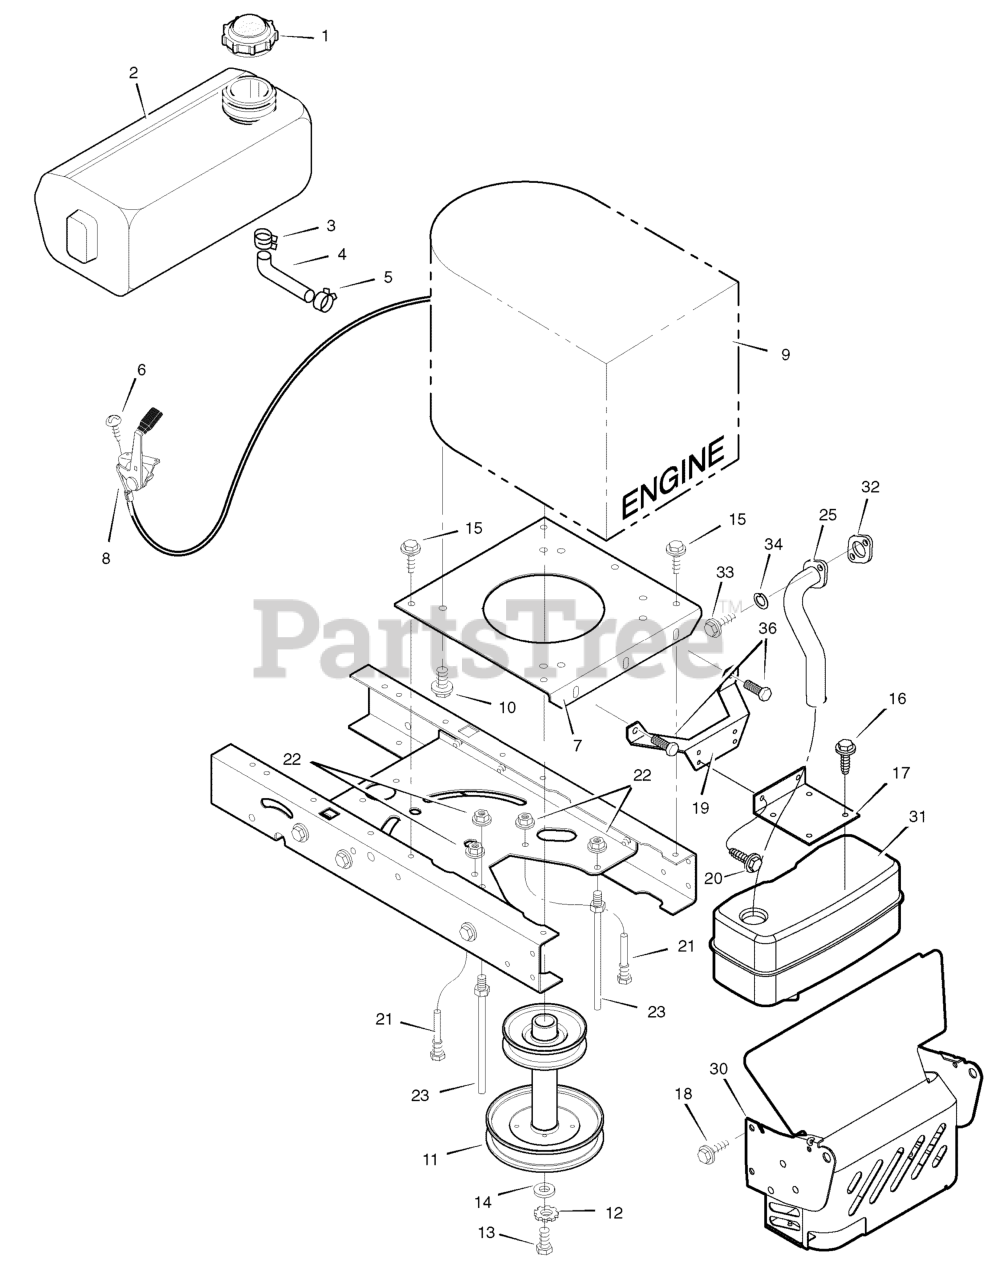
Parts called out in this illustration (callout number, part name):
1	Fuel Cap
2	Fuel Tank
3	Hose Clamp
4	Fuel Line (Must cut to length)
5	Hose Clamp
7	Plate, Engine
8	Throttle Control
9	Engine, Briggs & Stratton *
10	Bolt, Engine Mount
11	STACK PULLEY ASSEMBLY
12	Lockwasher
13	Bolt, Hex
16	Bolt, Muffler
17	Bracket, Muffler
19	Bracket, Muffler Mount
21	Guide, Belt
22	Nut, Flange
23	Guide, Belt
25	Exhaust, Tube Single
30	Shield, Heat
31	Muffler
32	GASKET, Exhaust
33	Screw, Adapter
34	Washer, .31 .58 x .07 Split
